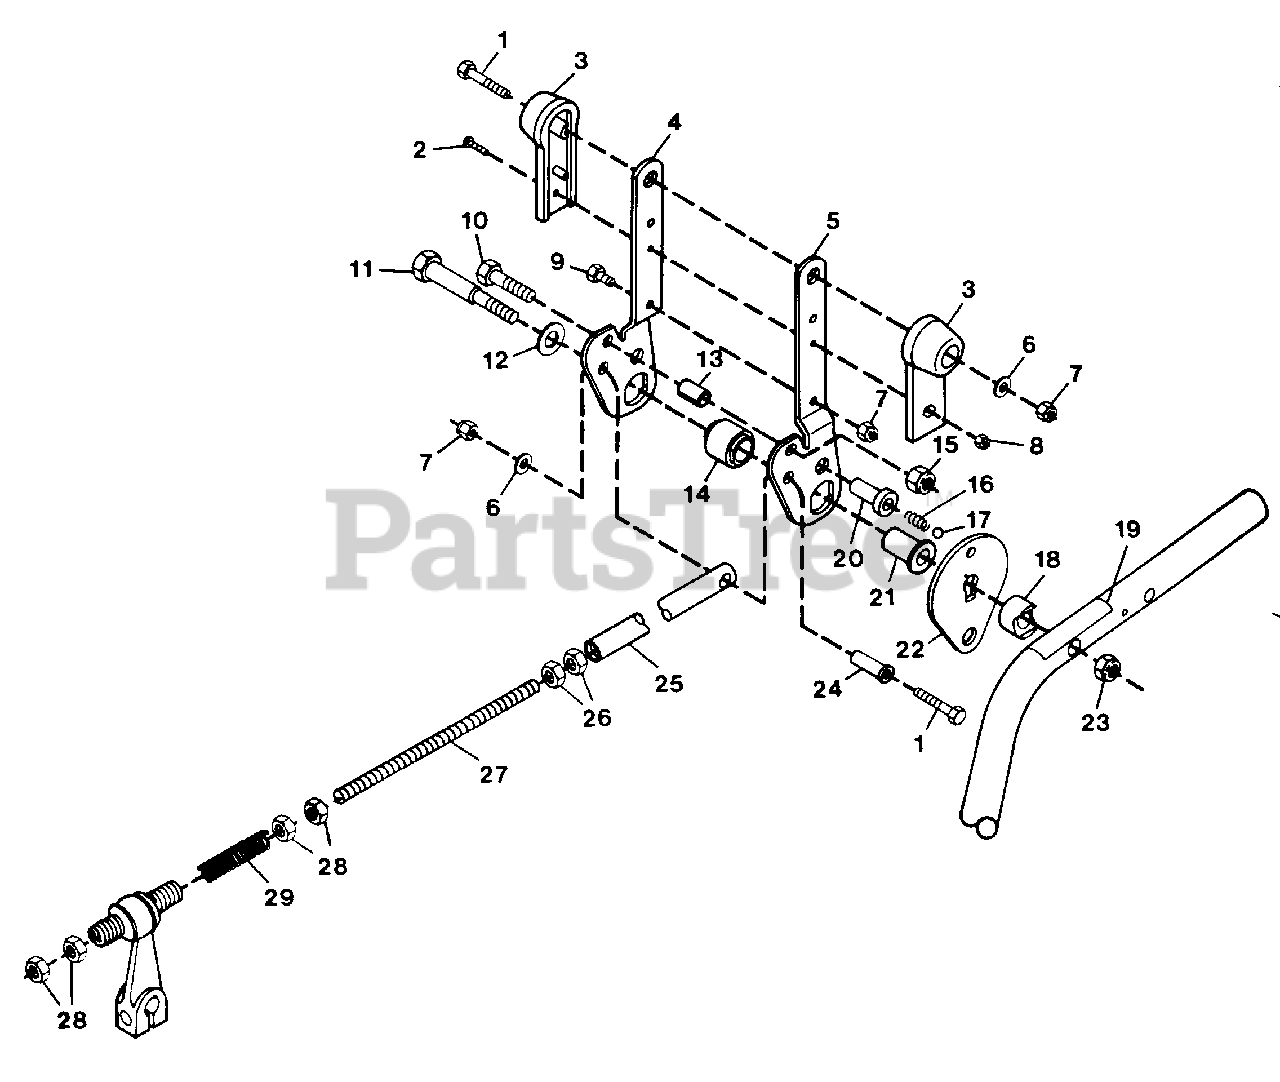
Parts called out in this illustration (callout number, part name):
1	BOLT, HEX 1/4-20X1.50
2	SCREW, MACHINE 6-32X.625 PHD
3	KNOB, HANDLE CONTROL
4	HANDLE, CONTROL R.H.
5	HANDLE, CONTROL L.H.
6	WASHER, FLAT .281X.625X.065
7	NUT, LOCK 1/4-20
8	NUT, LOCK 6-32
9	BOLT, HEX 1/4-20X.625
10	BOLT, HEX 3/8-16X1.50
11	BOLT, HEX STEP
12	WASHER, FLAT .531X1.062X.095
13	SLEEVE, HANDLE STOP
14	BUSHING, HANDLE
15	NUT, LOCK 3/8-16
16	SPRING, COMP. 7/8X.28
17	BALL, STEEL 5/16
18	BRACKET, HANDLE PIVOT
19	DECAL, FWD-REV
20	BUSHING, NEUTRAL
21	PIVOT, HANDLE
22	PLATE, NEUTRAL
23	NUT, LOCK 1/2-13 E.T.
24	BUSHING, OPER. PRESENCE HANDLE
25	ROD, CONTROL FWD-REV
26	NUT, HEX 3/8-16
27	ROD, CONTROL EXTENSION
28	NUT, JAM 3/8-16 HEX
29	SPRING, FWD-REV NEUTRAL RETURN
